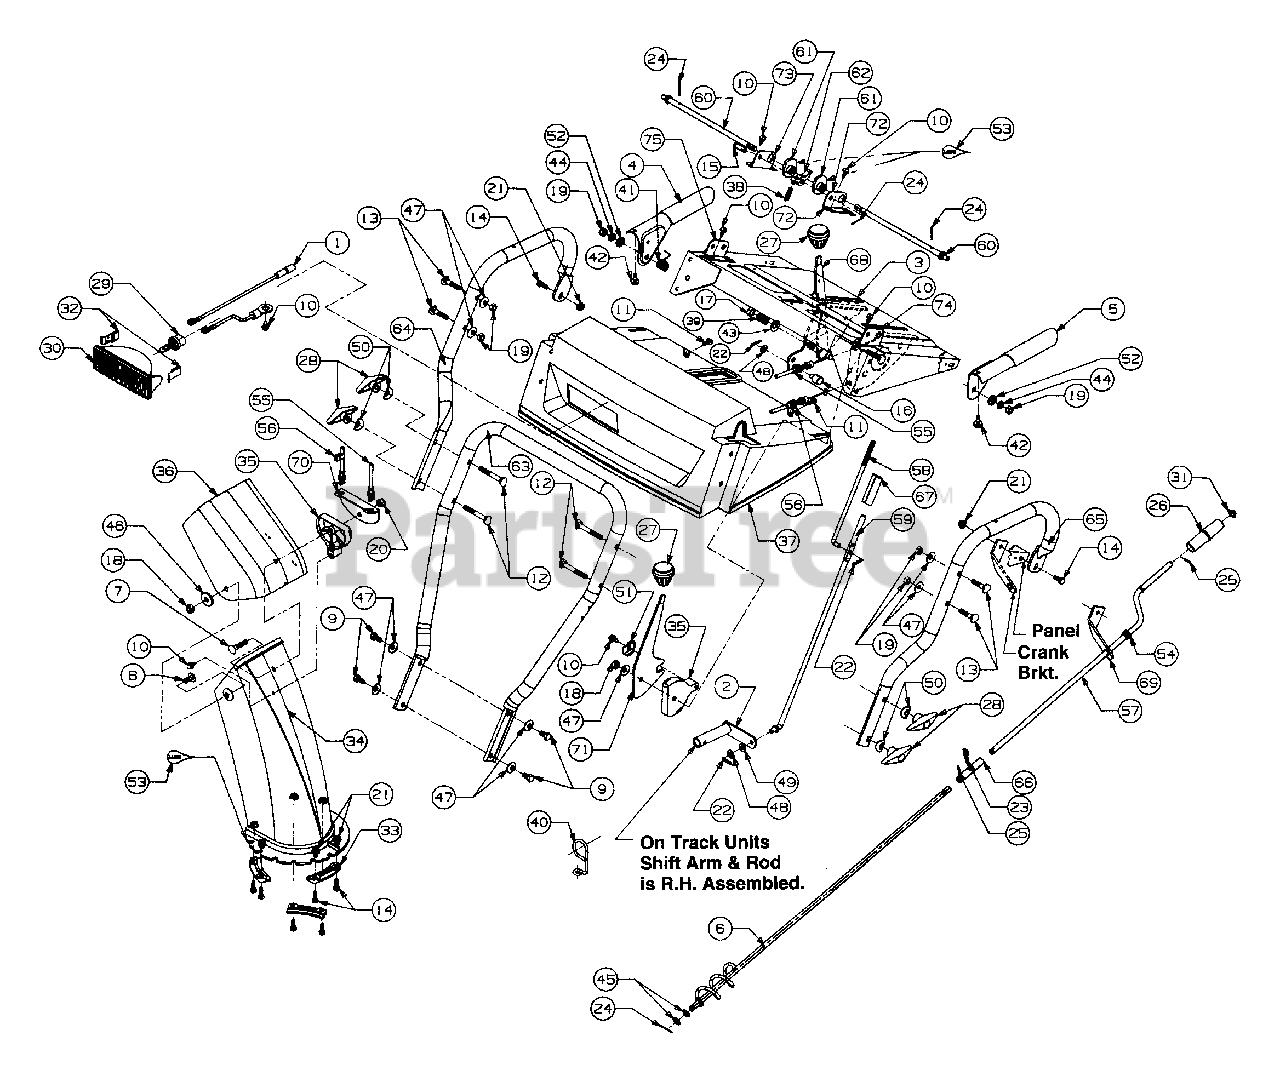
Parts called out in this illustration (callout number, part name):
1	Harness, Snowthrower Light
5	Handle, Engagement L.H.
8	Bolt, Carriage
9	Hex Screw
10	Hex Screw
11	Screw, Hex
12	Bolt, Curved Carriage
13	Bolt, Curved Carriage
14	Hex Cap Screw
15	Pin, Clevis
16	Ferrule, Engagement
17	Hex Lock Nut
18	Nut, Hex Lock
19	Nut, Hex
20	Hex Ins. L-Nut 5/16-18
21	Nut, Lock, Hex Flanged
22	Pin, Cotter
23	Pin, Cotter
24	Pin, Cotter
25	Roll Pin
26	Knob, Chute Crank
27	Knob, Shift
29	Lamp, Halogen
30	Housing, Lamp, Lens Assembly
31	Cap, Push
32	Clip, Retaining
33	Chute, Flange Keeper
34	Lower Chute, 5" Dia. Plastic
35	Cable Guide
36	Chute, Upper 5.0 Dia. Remote
37	Panel Handle
38	Spring
39	Spring
40	Cable Control Wire
41	Spring
42	Bumper
43	Washer, Bell
44	Lock Washer
45	Flat Washer
46	Washer
47	Washer, Bell
48	Washer, Flat
49	Washer
50	Washer, Saddle
51	Washer
52	Washer
53	Lubricant
54	Bushing, Plastic
55	Cable, Chute Deflector
56	Cable, Chute Deflector w/Clip
57	Crank, Chute
58	Rod, Shift, Upper
59	Rod, Shift, Lower
60	Rod, Cam
61	Cam Handle Lock
62	Pawl Handle Lock
67	Connector, Clutch Rod
68	Shift Handle
